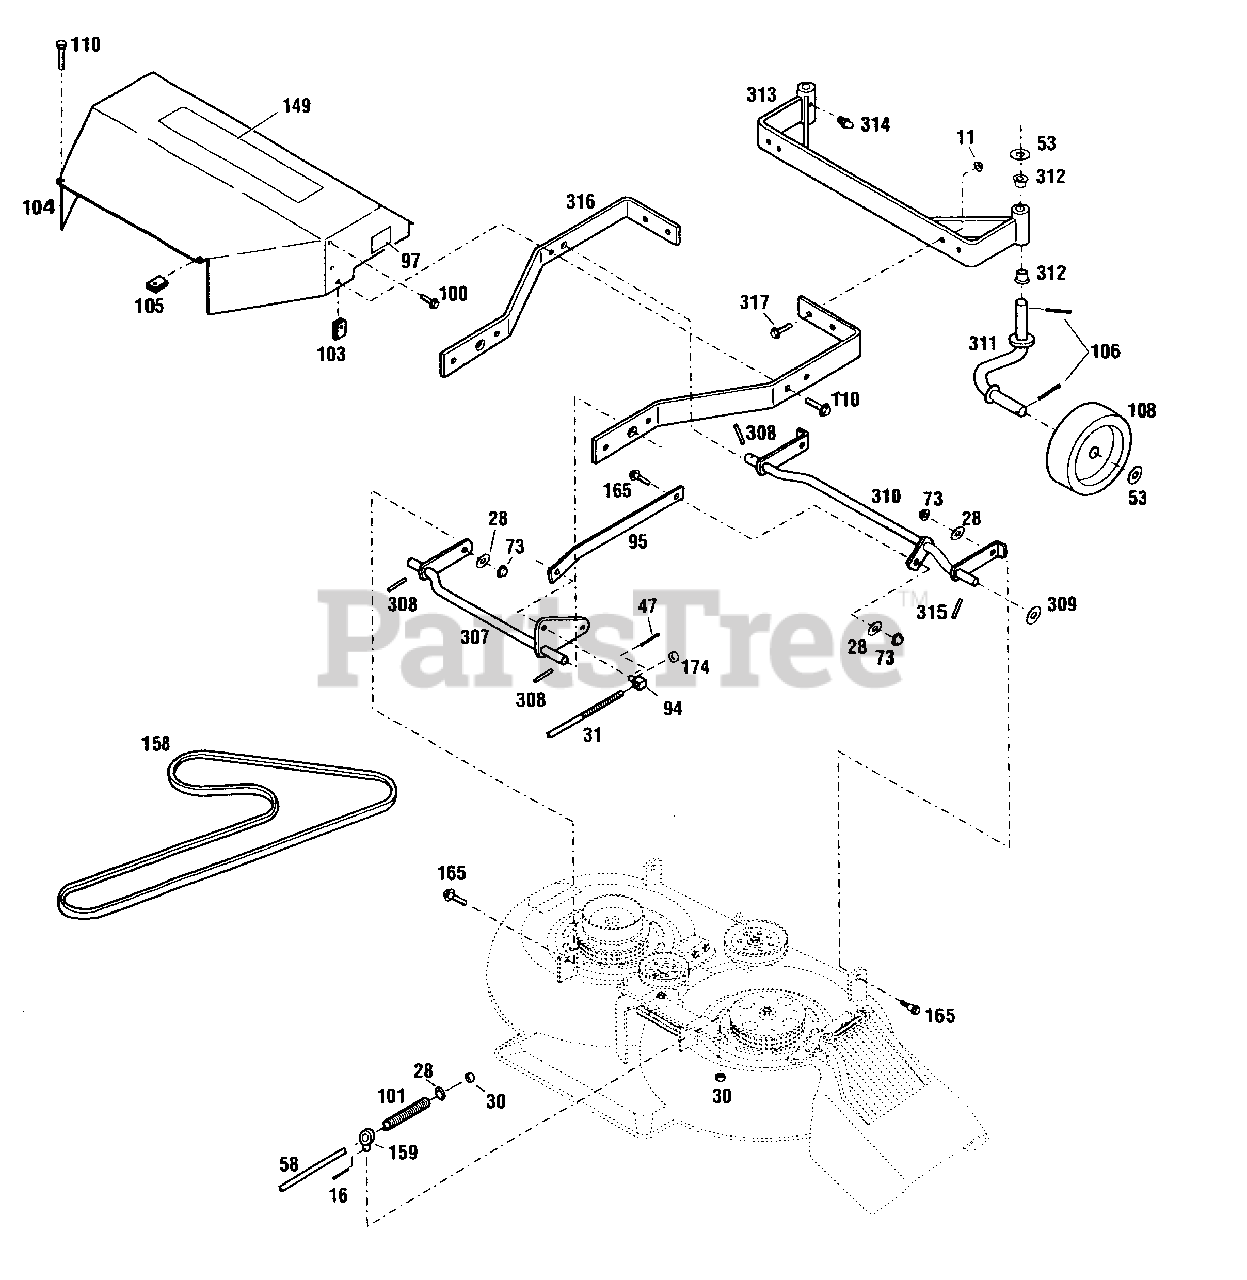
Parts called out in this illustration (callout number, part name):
11	Flange Locknut, 3/8-16
16	Cotter Pin, 3/32 x 5/8
28	Flat Washer, 3/8
30	Locknut, 3/8-16
31	Lift Crank
47	Cotter Pin
53	Special Washer
58	Lower Blade Rod
73	Flange Locknut, 3/8-16
94	Pivot Block
97	Cutting Height Decal
100	Tap Screw, #8 x 3/8
101	Compression Spring
103	Speed Nut, 5/16-18
104	Belt Guard
105	Speed Nut, 5/16-18
108	Gage Wheel
110	Flange Lock Screw, 5/16 x 3/4
165	Shoulder Bolt
174	Toplock Nut
307	Rear Lift Assembly
308	Roll Pin, 1/4 x1
309	Flat Washer, 5/8
310	Front Lift Assembly
311	Spindle Assembly
312	Flange Bearing
313	Gage Support
314	Grease Fitting
315	Drive Pin, 1/4 x 3
316	Mower Support
317	Whizlock Screw, 3/8-16 x 1
